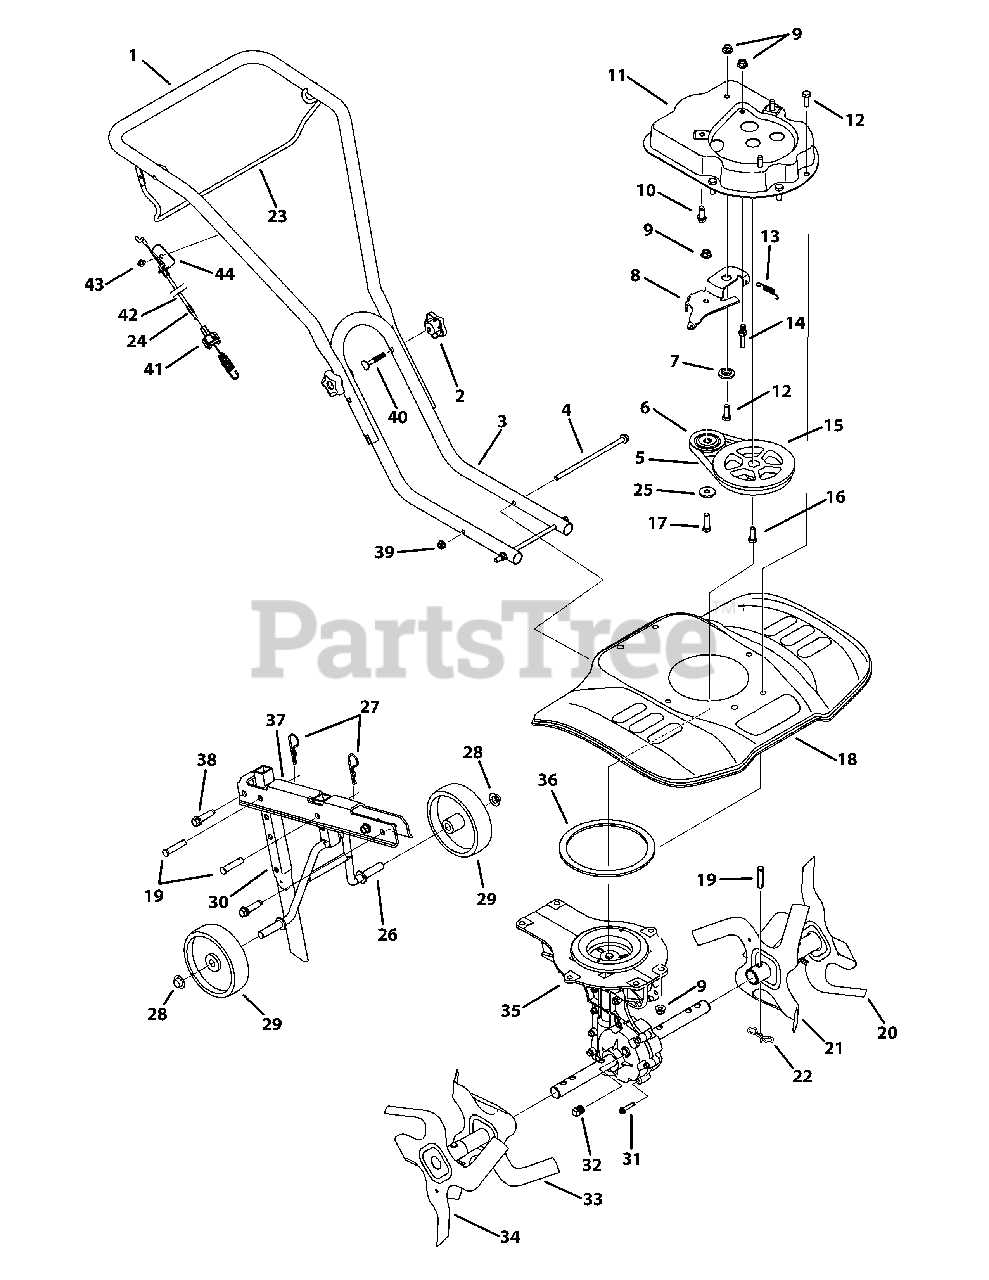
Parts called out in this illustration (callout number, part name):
1	Upper Handle
2	Star Handle Knob
3	Lower Handle
4	Flange Screw 5/16-18 x 7.5 x GR5
5	V-Belt
6	Idler Pulley
7	Shoulder Spacer
8	Idler Bracket
9	Flange Lock Nut x 3/8-16
10	TT Screw 3/8-16 x 1.00
11	Belt Cover
12	Hex Cap Screw 3/8-16 1.00
13	Extension Spring
14	Stud x 33 x 1.5 x 3/8-16
15	Flywheel Pulley
16	Hex Cap Screw 3/8-24 x 1.00
17	Hex Cap Screw 3/8-16 x 1.55
18	Tine Shield 61 cm
19	Clevis Pin
20	Outer Tine Assembly LH
21	Inner Tine Assembly LH
22	Cotter Pin, Bow Tie
23	Clutch Bail
24	Retaining Ring
25	Flat Washer, .406 x .875 x .059
26	Rear Wheel Tube Assembly
27	Cotter Pin
28	Push Cap
29	Wheel 5 x 1.38
30	Depth Stake Tube
31	TT Screw x 1/4-20 x 1.25
32	Pipe Plug 3/8 NPT
33	Inner Tine Assembly RH
34	Outer Tine Assembly RH
35	Case Assembly
36	Gasket
37	Wheel Bracket
38	TT Screw 3/8-16 1.50
39	Flange Lock Nut 5/16-18
40	Carriage Bolt
41	Clutch Cable Fitting
42	Clutch Cable
43	TT Screw 1/4-20 x .50
44	Cable Mount Bracket
